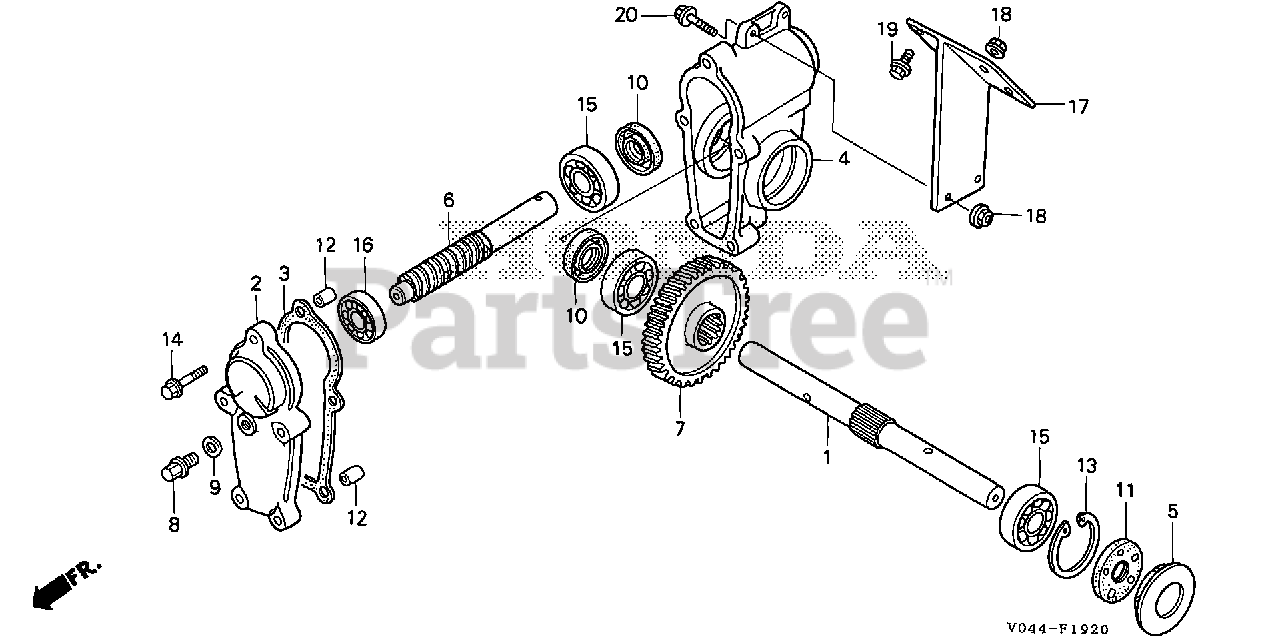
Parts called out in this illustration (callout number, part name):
1	SHAFT, AUGER
2	COVER, AUGER TRANSMISSION
3	GASKET, AUGER TRANSMISSION
4	CASE, AUGER TRANSMISSION
5	CAP, AUGER CASE
6	GEAR, DRIVE
7	GEAR, DRIVEN (55T)
8	BOLT, DRAIN PLUG
9	WASHER, DRAIN PLUG (10.2MM)
10	OIL SEAL (20X32X7)
11	OIL SEAL (20X42X8)
12	PIN A, DOWEL (8X14)
13	CIRCLIP (INNER) (42MM)
14	BOLT, FLANGE (6X32)
15	BEARING, RADIAL BALL (6004)
16	BEARING, RADIAL BALL (6202)
